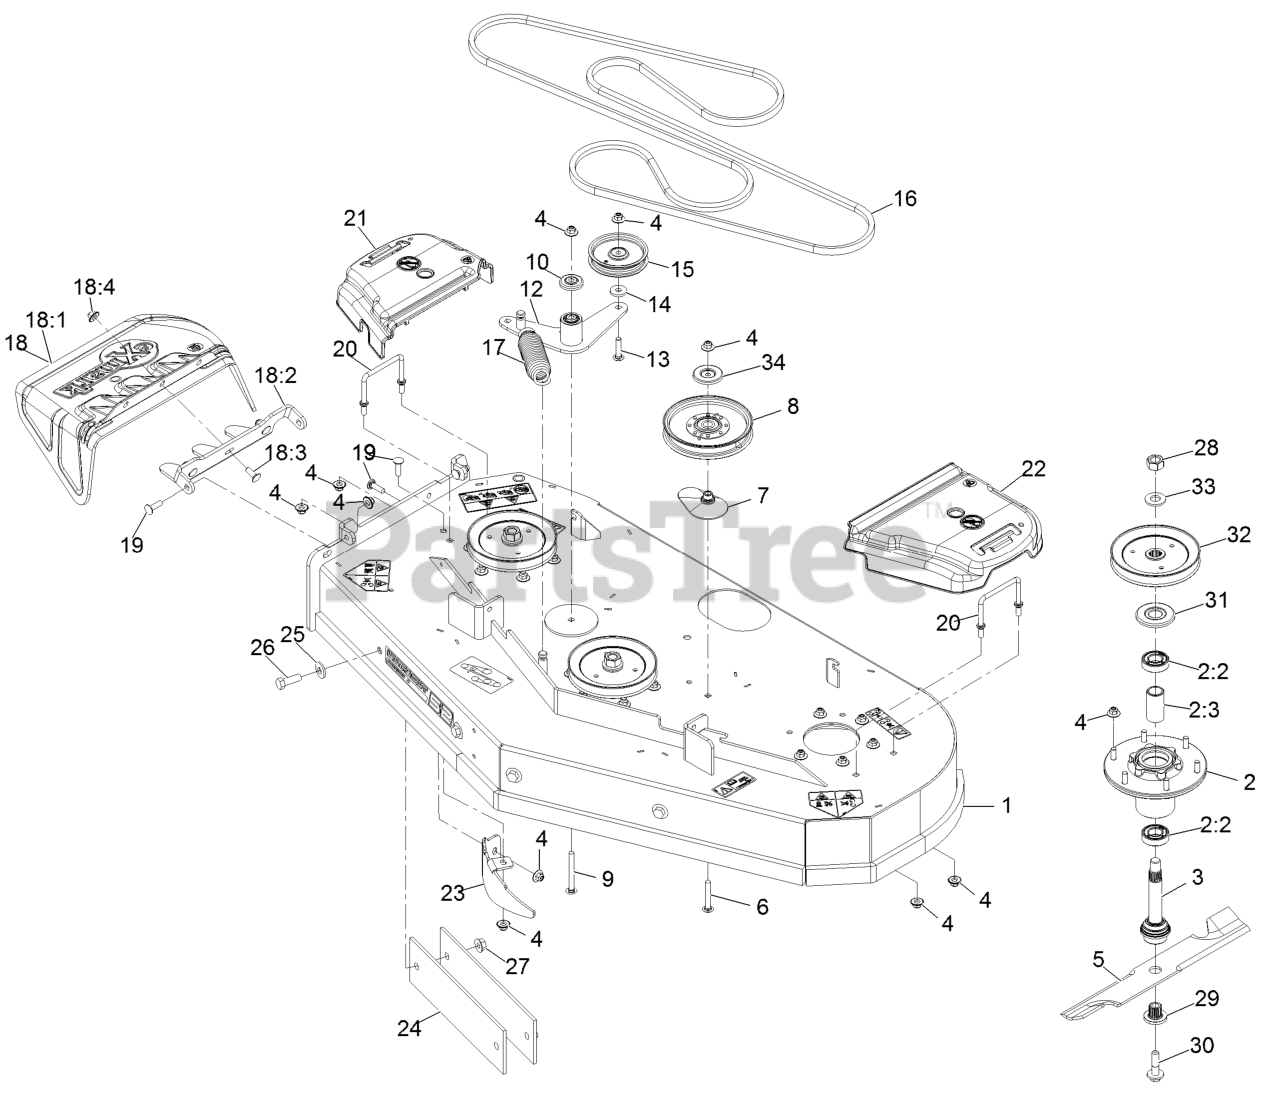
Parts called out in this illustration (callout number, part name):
1	DECK ASM-524
2	ASM-CUTTER HSG WITH BEARINGS
2:2	BEARING-BALL
2:3	SPACER-BEARING
3	ASM-SPINDLE AND SEAL
4	Nut-Nyloc 3/8-16 Flg
6	SCREW-CARR
7	SPACER-PULLEY
8	IDLER-PULLEY
9	SCREW-CARR
10	GUARD-TOP
12	IDLER ARM ASM W/BEARINGS
13	SCREW-CARR SPECIAL
15	PULLEY-IDLER
16	BELT-V
17	SPRING-EXTENSION
18	ASM,DISCHARGE CHUTE
18:1	CHUTE,DISCHARGE
18:2	BRACKET,DISCHARGE CHUTE
18:3	SCREW-CARR
18:4	Nut-Nyloc 3/8-16 Flg
19	Bolt-Carriage 3/8-16 X 1 1/4
20	WIREFORM-COVER
21	COVER-BELT, RH
22	COVER-BELT, LH
23	BAFFLE-DOGLEG, LZ-VT52
24	BAR,WEIGHT
25	WASHER-SPRING
26	SCREW-HH
27	NUT-HHF
28	NUT-HEX
29	BUSHING,SPLINED
30	SCREW,SEMS 1/2-20 X 2.19
31	GUARD,BEARING TOP .989
32	SHEAVE,BLADE DRIVE 6.50
34	SHIELD-DUST
